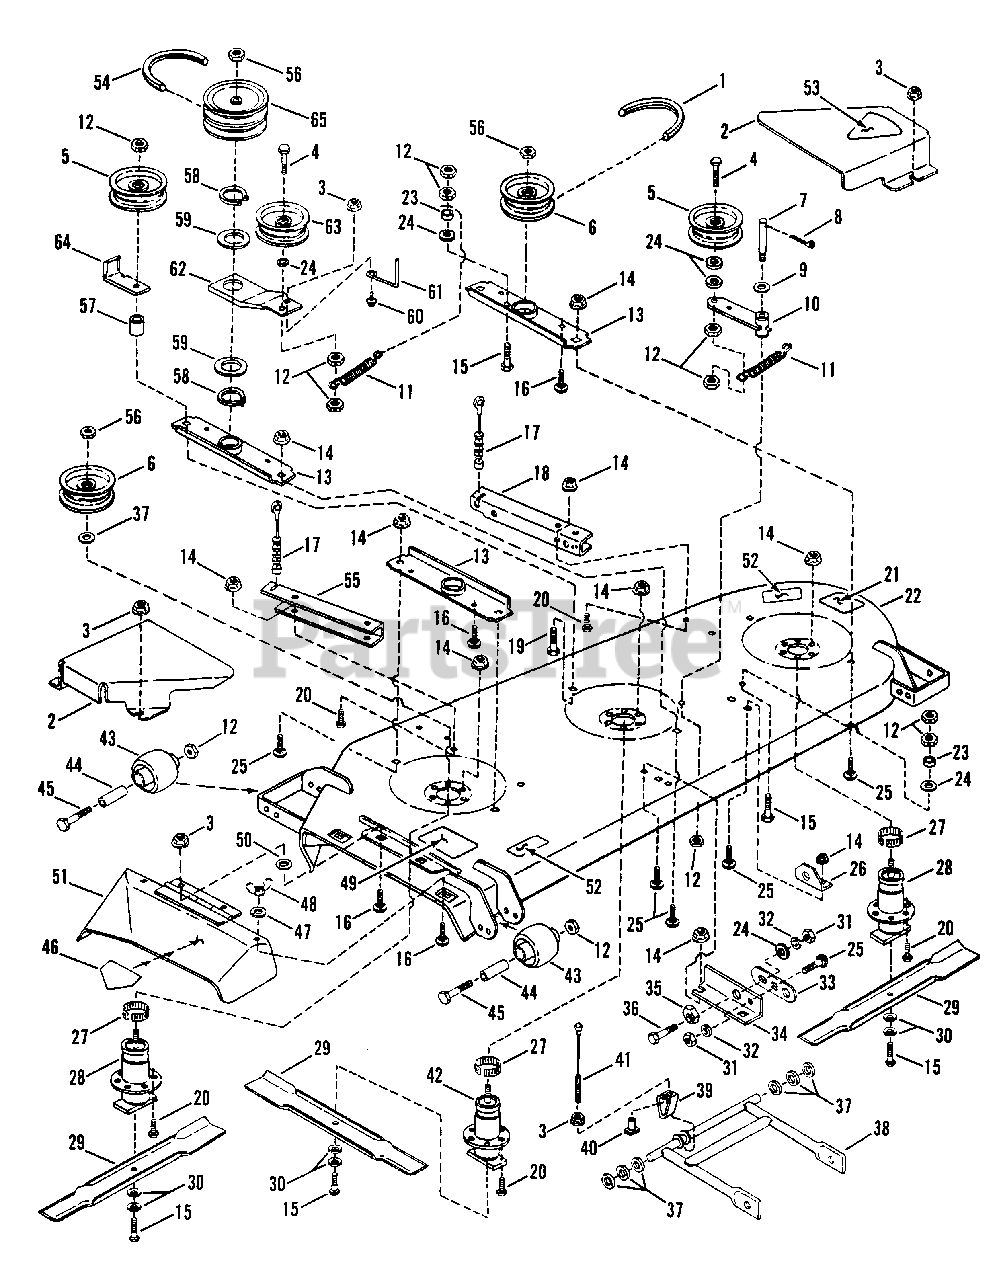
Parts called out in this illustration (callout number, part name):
1	V-BELT, 48" Cutting Deck
2	GUARD, Pulley
3	NUT, 5/16-18 Hex Fl. Lk., Gr. 5
4	SCREW, 3/8-24 x 2" H.H.C., Gr. 5
5	PULLEY, Idler, V, 4-1/2" O.D.
6	PULLEY, Idler, Flat, 4-3/4" O.D.
7	STUD, Idler
8	COTTER-PIN, 1/8 x 1"
9	WASHER, 5/8 SAE Flat
10	ASSEMBLY, Idler Arm
11	SPRING
12	NUT, 3/8-24 Hex Lock
13	BRACE, Spindle
14	NUT, 3/8-16 Hex Flange Lock
15	SCREW, 3/8-24 x 1-1/4" Gr.5
16	BOLT, 5/16-18 x 5/8 Carr. Gr. 5
17	CABLE, Lift
18	SUPPORT, Cable, Left Side (Rear)
19	SCREW, 3/8-24 x 2-1/2" H.H.C., Gr.5
20	BOLT, 3/8-16 x 3/4" Flange Lock
21	DECAL-CAUTION
22	DECK, 48" Cutter
23	SPACER
24	WASHER, 3/8 SAE
25	BOLT, 3/8-16 x 3/4" S.N.C., Gr.2
26	BRACKET, Front Hanger (Left Side)
27	RING, Tolerance, 3/4"
28	ASSEMBLY, Spindle
29	BLADE, 16.5"
30	WASHER, Cone
31	NUT, 3/8-16 Hex, Gr. 5
32	WASHER, 3/8 Split Lock
33	LINK, Adjustment
34	BRACKET, Front Hanger (Right Side)
35	RING, Adjustment
36	SCREW, 3/8-16 x 1" H.H.C., Gr. 5
37	WASHER, 3/4 I.D.
38	ARM, Front Lift
39	BRACKET, Front Lift Arm
40	T-NUT, 5/16-18
41	CABLE, Front Lift
42	ASSEMBLY, Spindle
43	WHEEL, Gage, Front
44	SPACER
45	SCREW, 3/8-24 x 3-3/4", Gr. 5
46	DECAL-DANGER
47	WASHER, 5/16 Split Lock
48	WING-NUT, 5/16-18
49	DECAL- CAUTION, Deflector in Place
50	RETAINER, 5/16 Bolt
51	ASSEMBLY, Side Chute
52	FOOTPAD
53	DECAL - 48 Inch
54	V-BELT, Drive, A92
55	SUPPORT, Cable, Right Side (Rear)
56	NUT, 3/4-16 Hex Jam Lock
57	SPACER
58	RING, 2" External Retaining
59	WASHER, Plastic
60	BOLT, 5/16-18 x 3/4" S.N.C., Gr. 5
61	GUIDE, Belt
62	ARM, Idler, Center
63	PULLEY, Idler, Flat, 4.8" O.D.
64	GUIDE, Belt
65	PULLEY, Double, 5" O.D. & 4-3/4" O.D.
